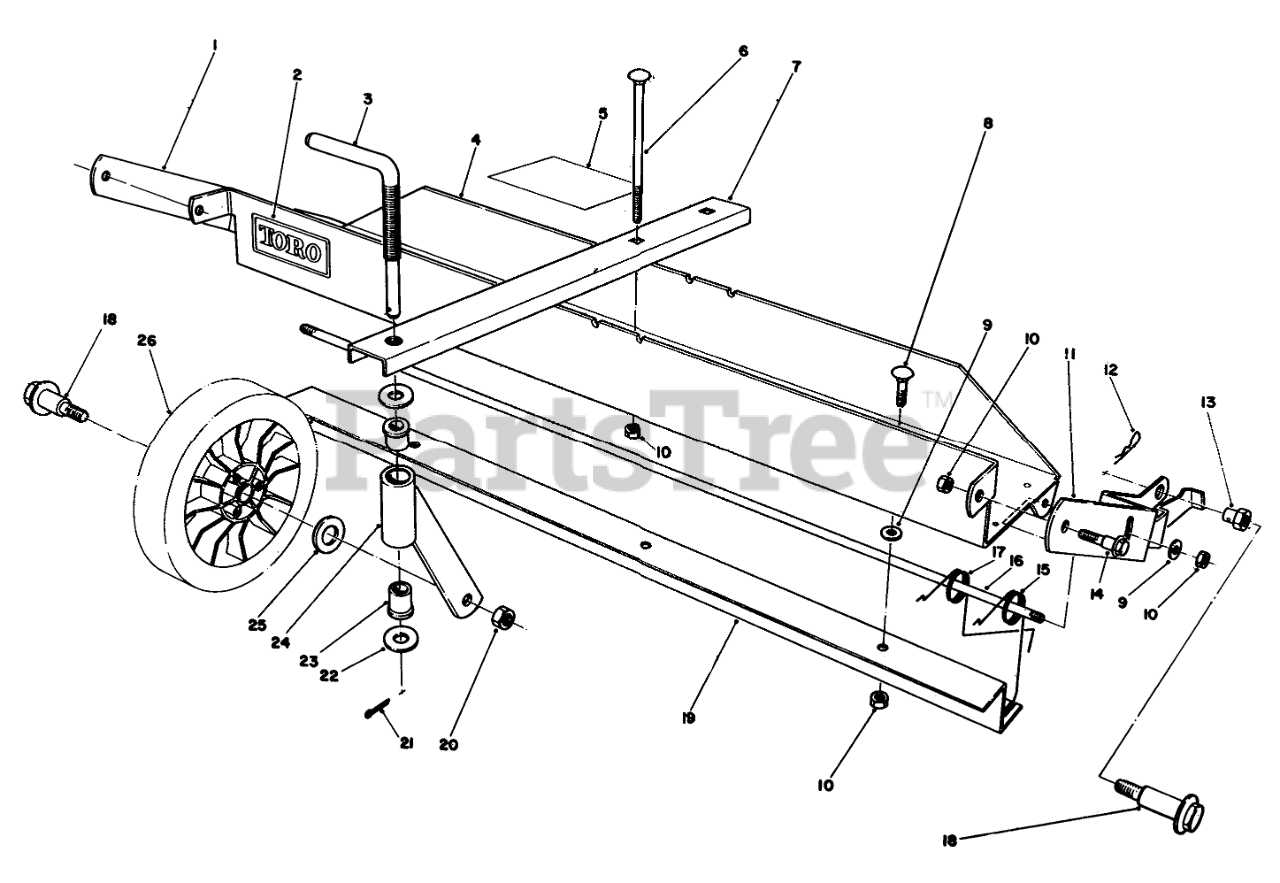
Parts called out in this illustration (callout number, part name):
1	Frame R.H.
2	Decal-Toro
3	CASTOR ADJ ROD
4	Frame-Main (Incl. Ref. #2)
5	Decal-Instruction
6	SCREW-CARR
7	Castor Frame
8	BOLT-CARR
9	WASHER-FLAT
10	NUT-HEX, SIDE DEFORM
11	LH MTG FRAME
12	PIN-COTTER, HAIR
13	PIVOT NUT
14	SCREW-SHOULDER
15	DETHATCHER SPRING
16	SPRING SUPPORT ROD
17	DETHATCHER SPRING
18	BOLT-WHEEL
19	SPRING GUIDE STRAP
20	NUT-LOCK
21	PIN-COTTER
22	WASHER-FLAT
23	FLANGE BUSHING
24	Castor Tube & Support
25	Wheel Assembly
